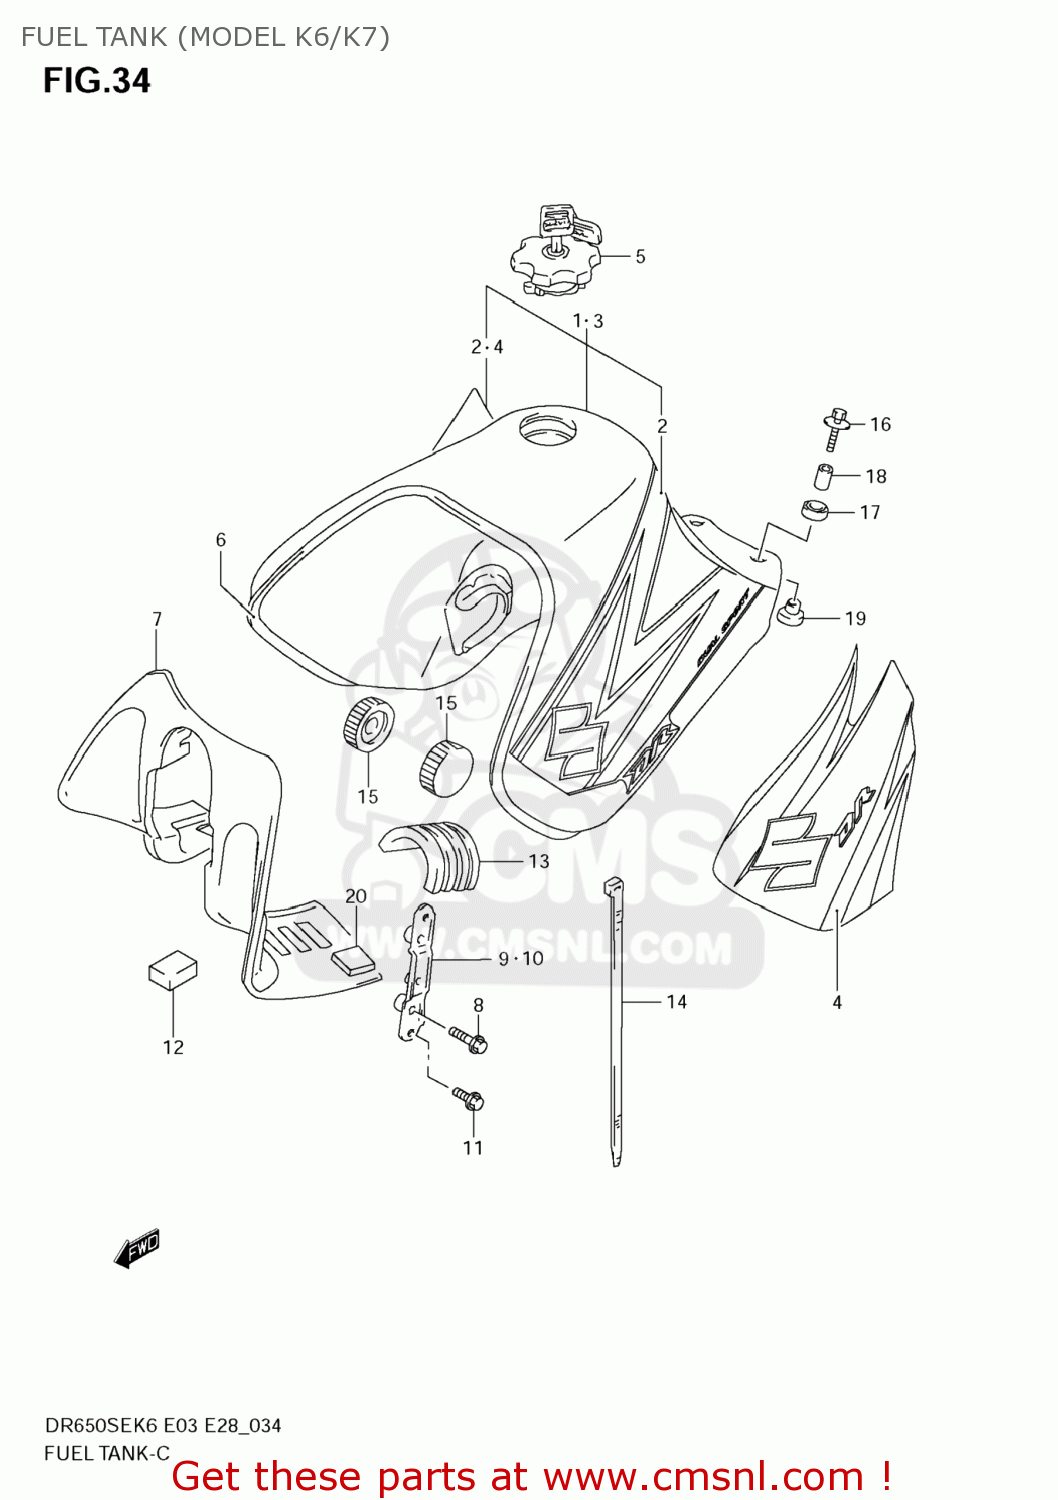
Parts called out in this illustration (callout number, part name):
1	TANK ASSY,FUEL(YELLOW)
2	TAPE SET,FUEL TANK
3	TANK ASSY,FUEL(BLUE)
4	TAPE SET,FUEL TANK
5	CAP SET,FUEL TANK
6	MOLDING,FUEL TANK
7	COVER,FUEL TANK FR
8	BOLT(6X12)
9	BRACKET,FUEL TANK COVER,R
10	BRACKET,FUEL TANK COVER,L
11	BOLT
12	CUSHION,HEAD LAMP HOUSING
13	CUSHION,FUEL TANK UPR
14	CLAMP(L:250)
15	CUSHION,FUEL TANK FR
16	BOLT(6X30)
17	CUSHION
18	SPACER(6.5X9X18)
19	CUSHION
20	CUSHION,OIL TANK UPR
